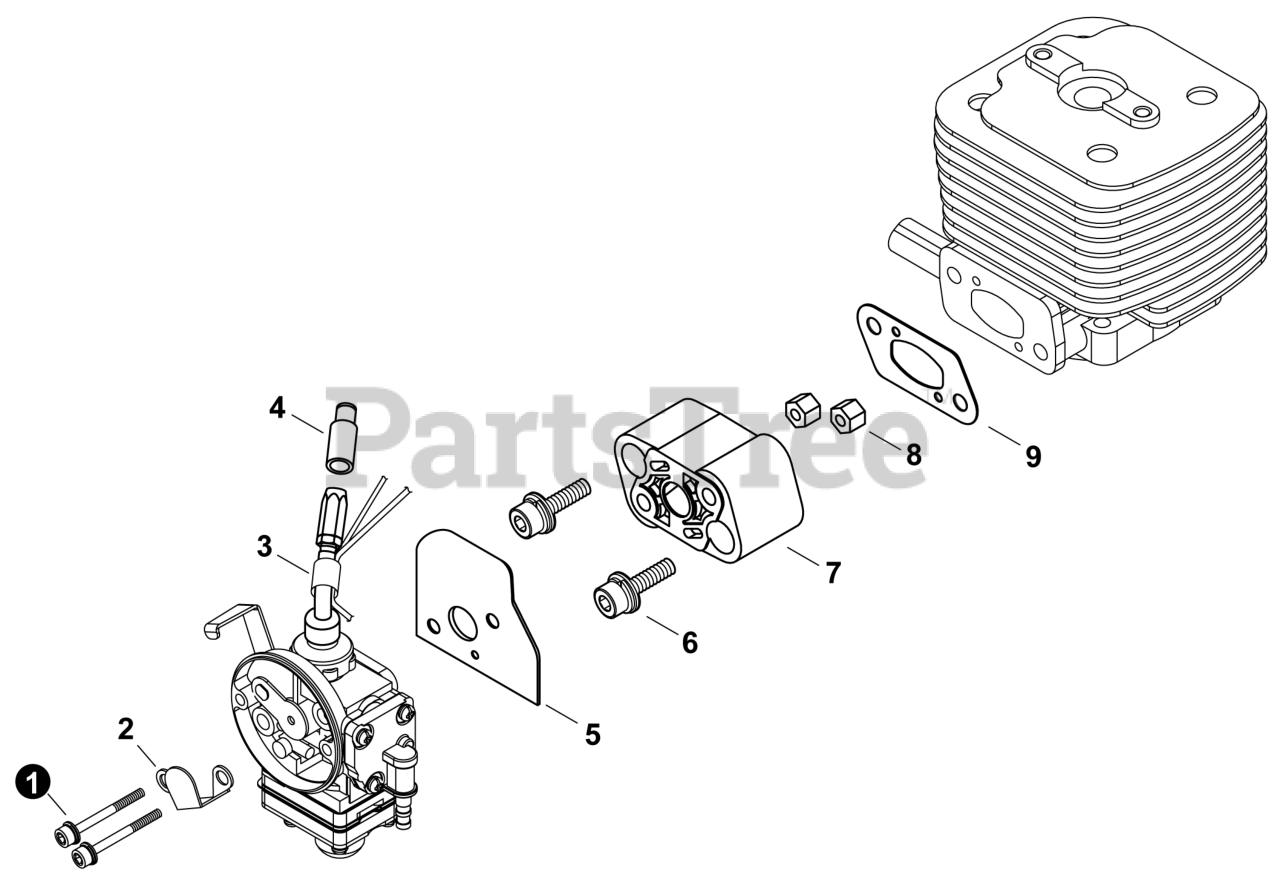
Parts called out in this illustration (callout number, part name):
2	PLATE, PREVENT
3	TUBE, PROTECTIVE
4	CAP, CARBURETOR
5	GASKET, CARBURETOR
6	BOLT M5x25
7	INSULATOR
9	GASKET, INTAKE
